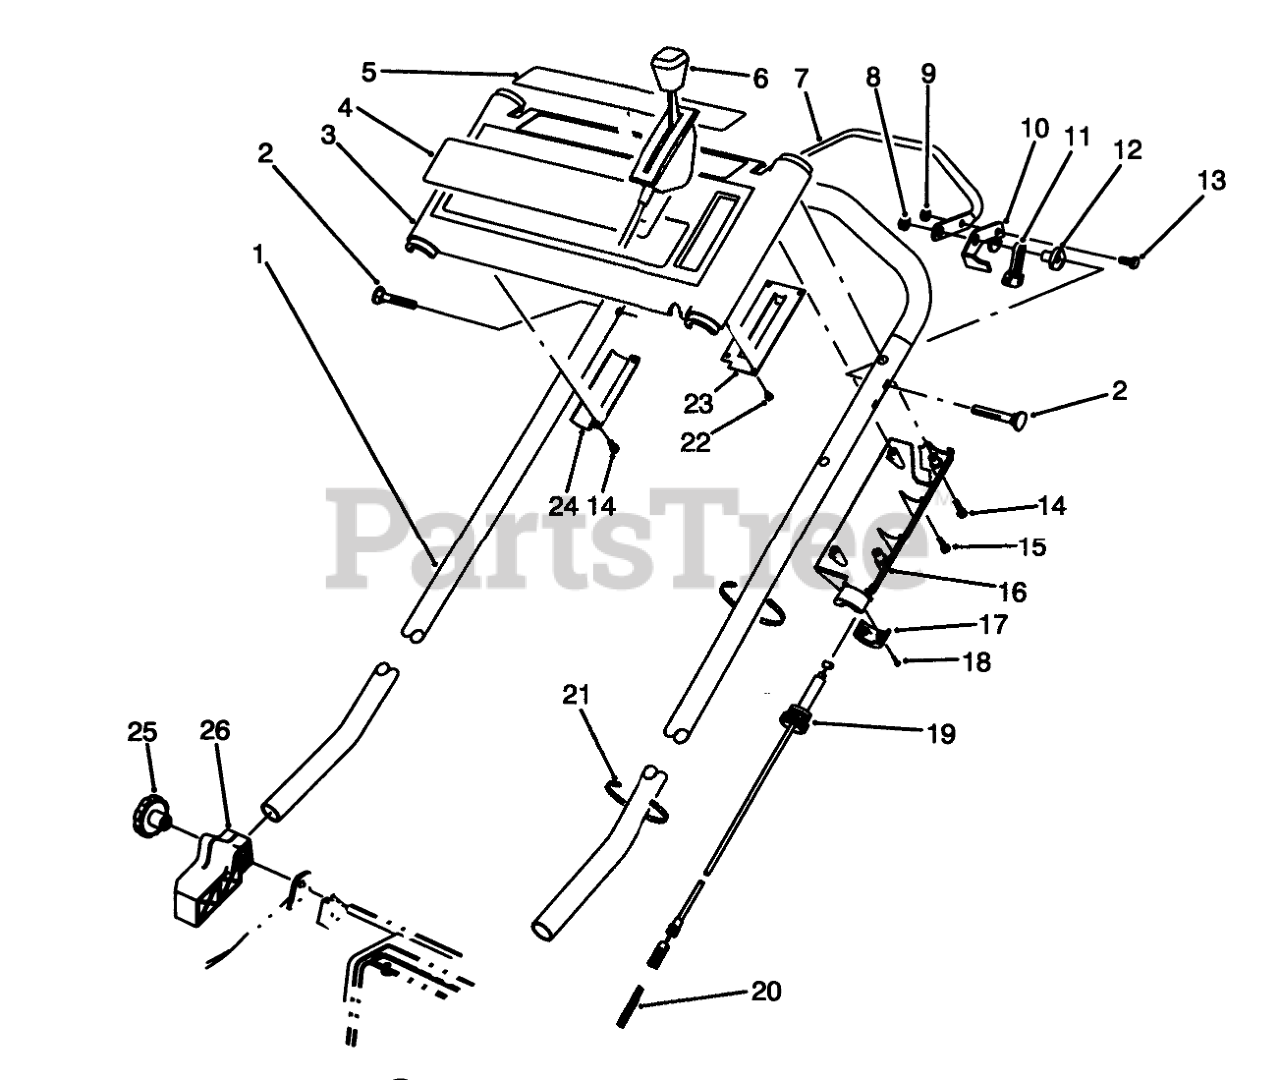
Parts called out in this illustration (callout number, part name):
1	Handle
2	SCREW-HANDLE
3	Panel-Control (Incl Ref. #4, & 5)
4	DECAL - PANEL OHV
5	DECAL - PANEL (DANGER)
6	THROTTLE CONTROL
7	CONTROL BAR
8	NUT-LOCK, NI
9	NUT-LOCK, NI
10	CONTROL LEVER
11	LEVER-TRACTION
12	SPACER-SUPPORT
13	SCREW-HH
14	SCREW-PPH, PLASTITE
15	Screw
16	Cover-Throttle Lower
17	LOWER THROTTLE CAP
18	#4-14X.62 PLASTITE SCW
19	TRACTION CABLE
20	SPRING-COMPRESSION
21	TIE-CABLE
22	#6-19X.25 PLASK FORM SC
23	THROTTLE PLATE
24	Bracket-Panel
26	MOUNT-HANDLE, RH
